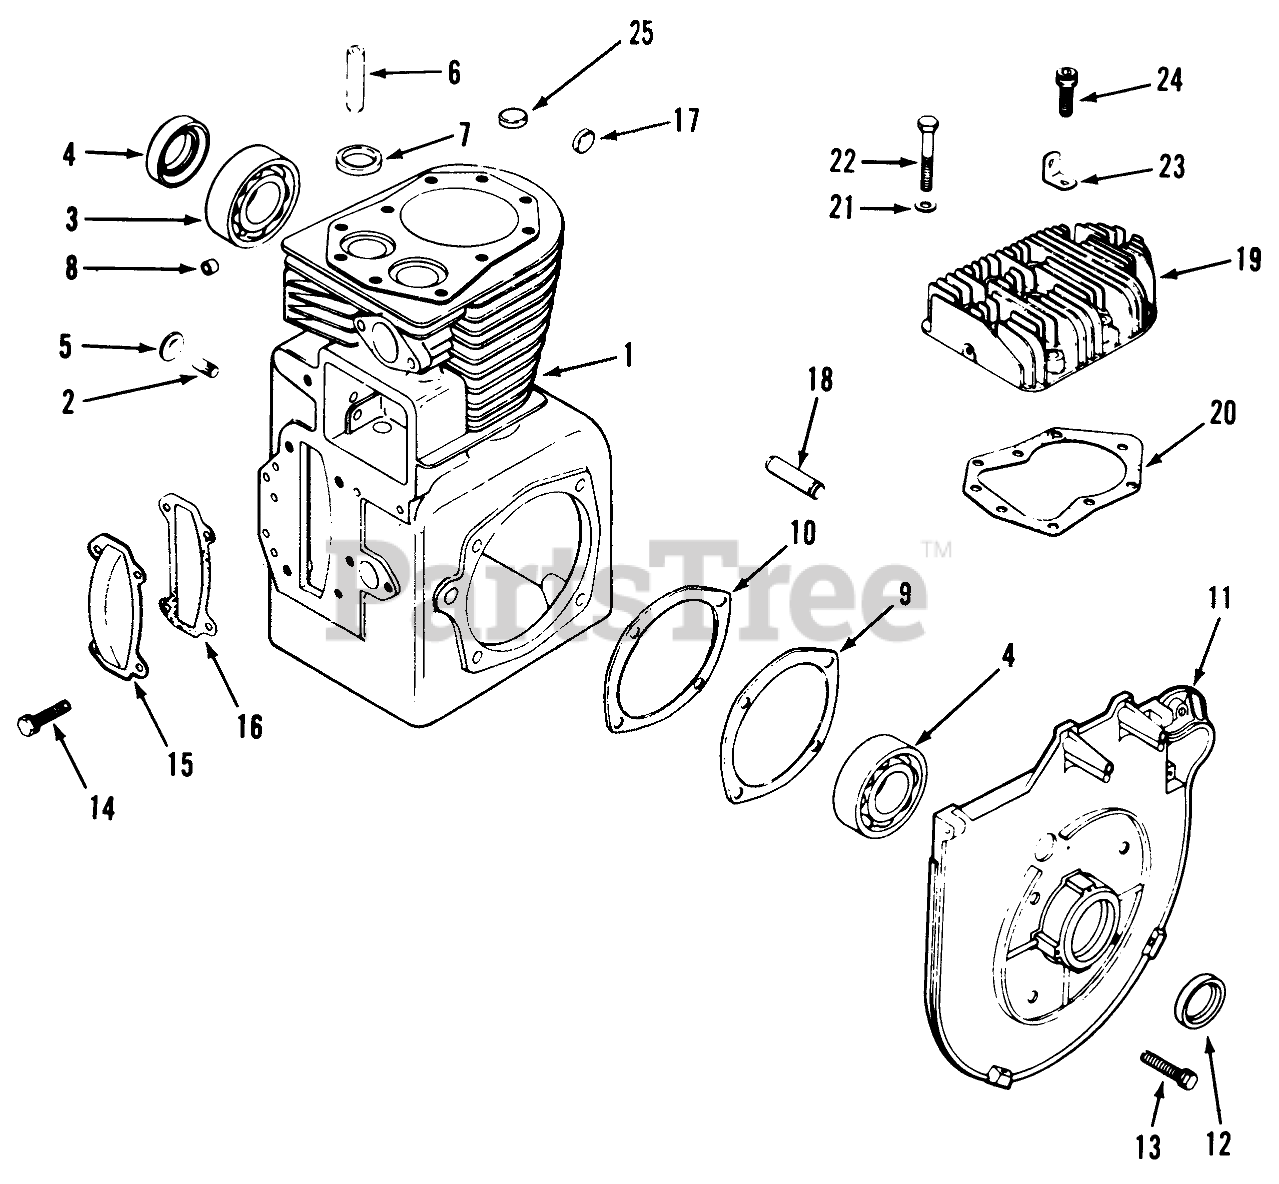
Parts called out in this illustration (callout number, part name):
1	Cylinder Block-Service With Short Block (Includes Crankshaft
2	Governor Gear Shaft
3	Ball Bearing
6	Guide-Valve
7	Exhaust Valve Insert
8	Bearing
9	Gasket
10	Gasket
11	Bearing Plate
13	Screw
14	Screw
15	Cover
16	Gasket
17	Plug 5/16 O.D. 310
18	Shaft-Balance Gear
19	Cylinder Head
20	Gasket
21	Washer
22	Screw
23	Lifting Strap
24	Screw
25	Plug Cup (310 only)
